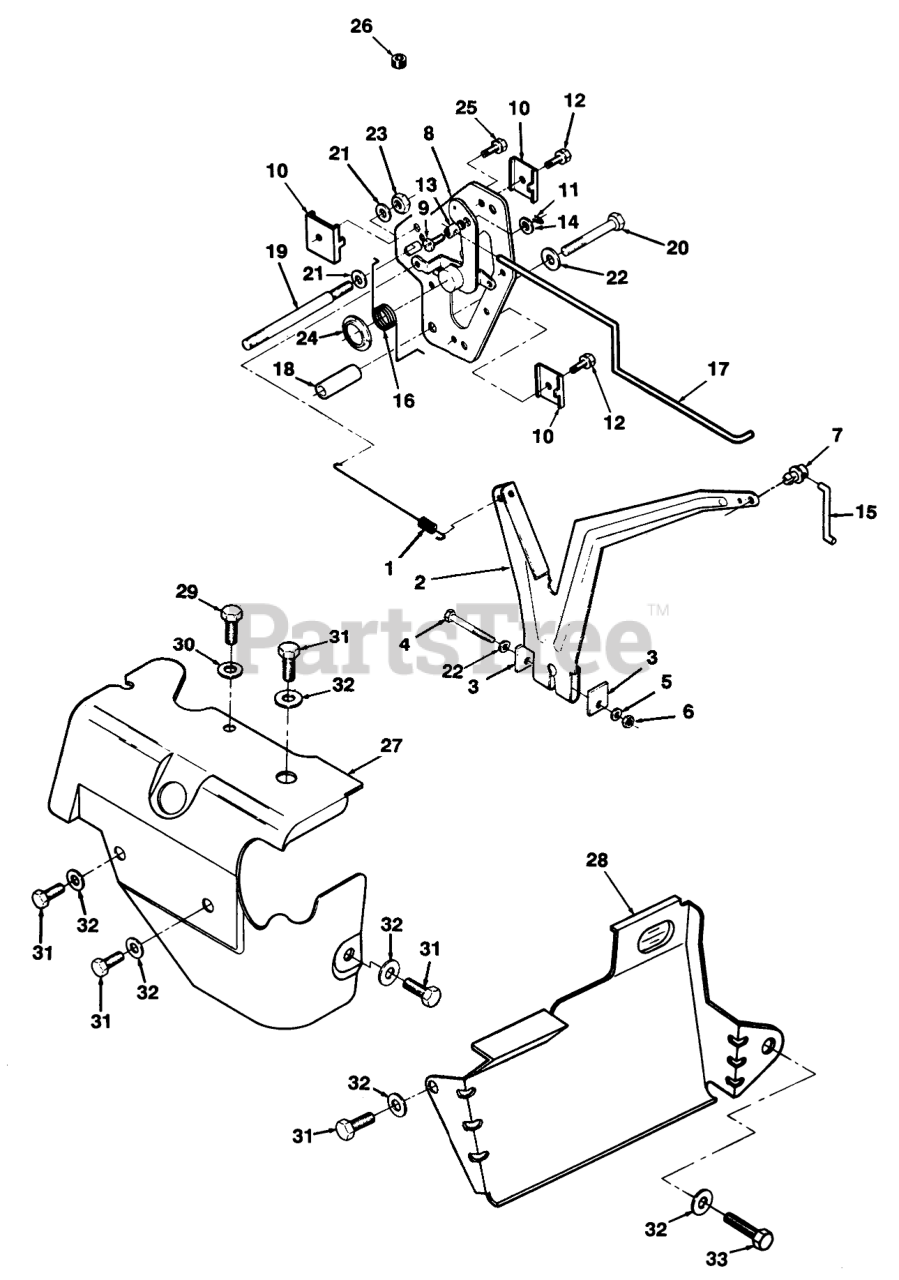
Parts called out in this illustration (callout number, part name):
1	SPRING-GOVERNOR
2	LEVER-GOVERNOR
3	WASHER
4	HHCS-M8 X 35MM
5	WASHER
6	Nut
7	Clip
8	PLATE-ASS'Y THROTTLE
9	HHMS #8-32X3/8"
10	Plug-Pipe
11	PIN-COTTER
12	SCREW-TAPPING
13	SWIVEL-CHOKE LEVER
14	Washer
15	LINK-THROTTLE
16	SPRING-CHOKE LINKAGE
17	LINK-CHOKE
18	SPACER
20	SCREW
21	WASHER-FLAT
22	WASHER-FLAT
23	NUT-HEX M6
24	Retaining Ring
25	STFHWH 12-24 X 1"
26	Plug
27	HSG-CYL AIR
28	Air Deflector
29	HHCS-M6 X 10MM
30	WASHER-FLAT
31	HHCS-M8 X 10MM
32	WASHER-FLAT
33	HHCS-M8 X 16MM
